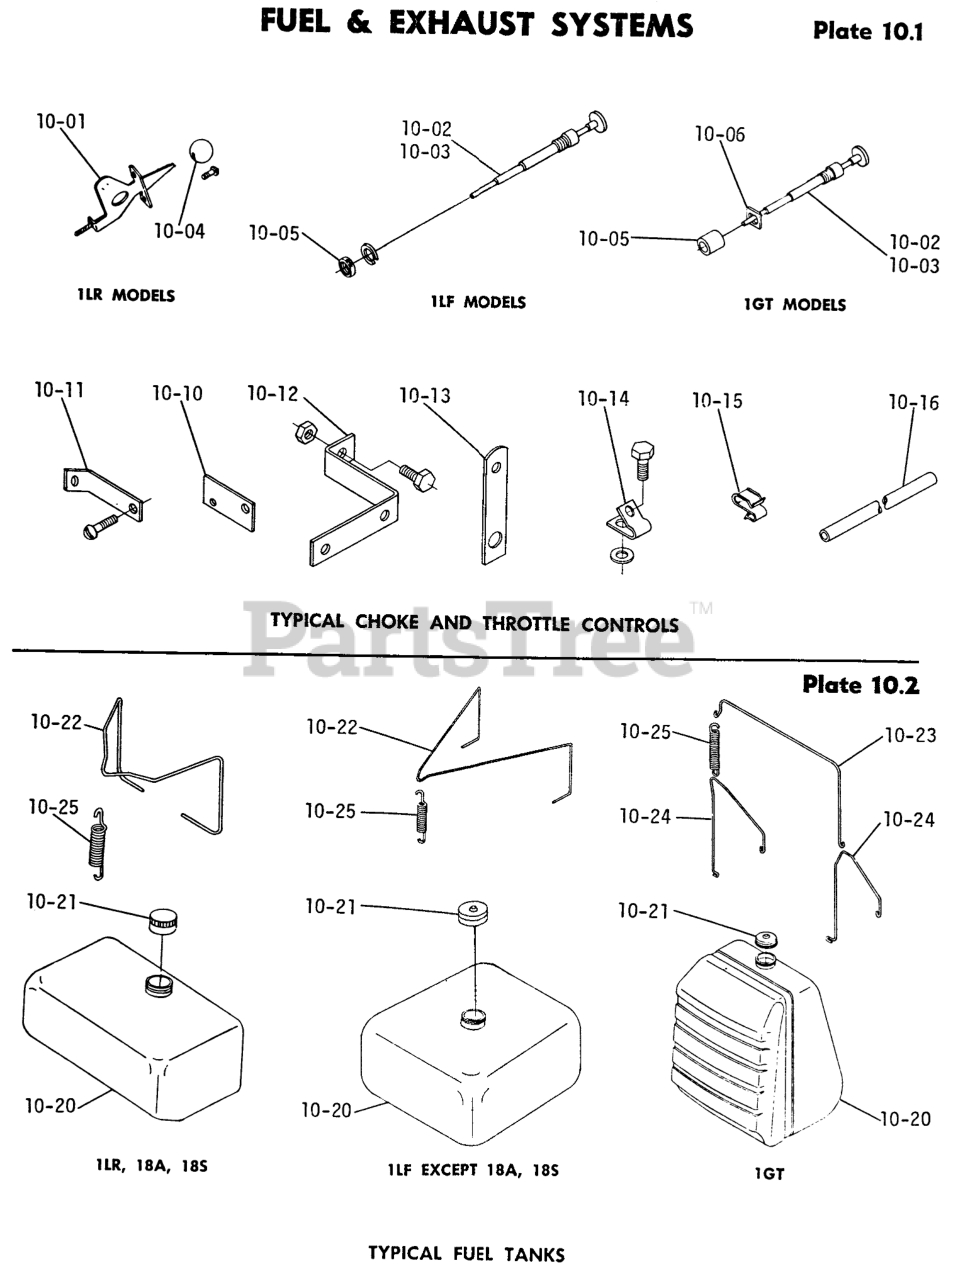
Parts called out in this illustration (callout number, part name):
10-01	Pin Oval Head
10-01	Bolt 1/4-20 x 1/2
10-05	RING NUT
10-05	Lockwasher 9/16
10-11	Bracket-Choke engine front
10-11	Screw, #10-32 x 5/8
10-12	Bracket-Choke engine top
10-12	Bolt 1/4-20 X 3/4
10-12	Bolt, 1/4-x 1/2
10-12	Nut, 1/4-20
10-14	Nut, 1/4-20
10-14	CLIP BOWDEN WIRE
10-14	Screw #10 x 1/2 Type A
10-14	Speed Nut
10-14	Bolt 1/4-20 x 3/8
10-14	Nut-Nylok
10-14	Bolt, 1/4-x 1/2
10-14	THROTTLE CONTROL CLP
10-14	CLIP-CABLE
10-16	Cover-Cable
10-22	HOLD DOWN WIRE
10-23	Wire-Tank Hold Down-top
10-24	Wire-Fuel Tank Hold Down
